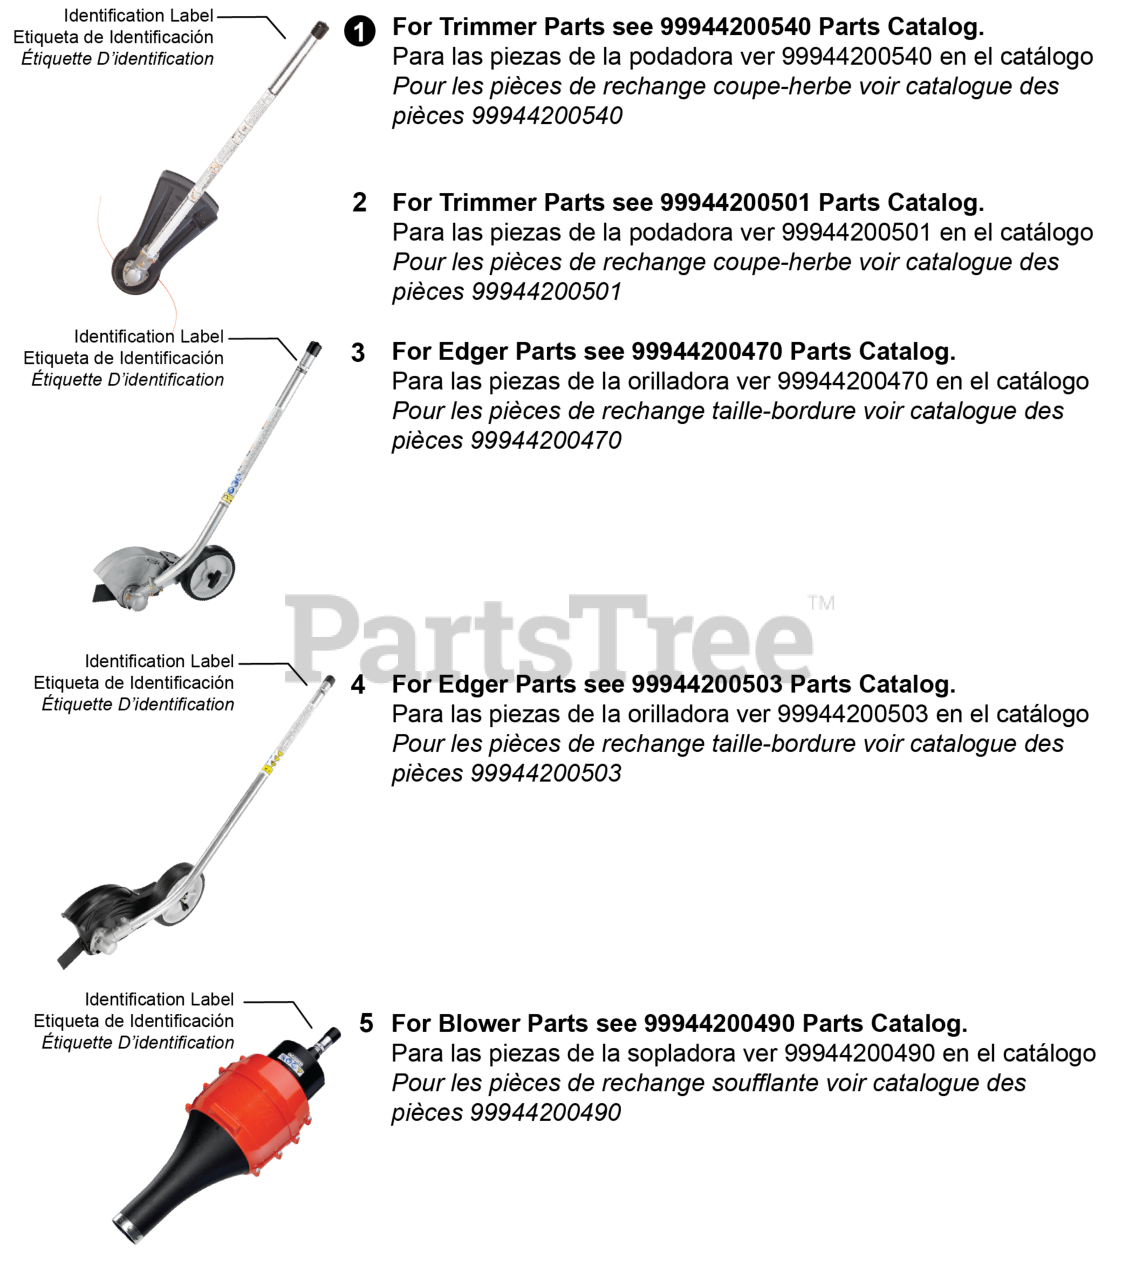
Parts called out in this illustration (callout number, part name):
1	TRIMMER ATTACHMENT
2	TRIMMER ATTACHMENT
3	EDGER ATTACHMENT
4	EDGER ATTACHMENT
5	BLOWER ATTACHMENT
